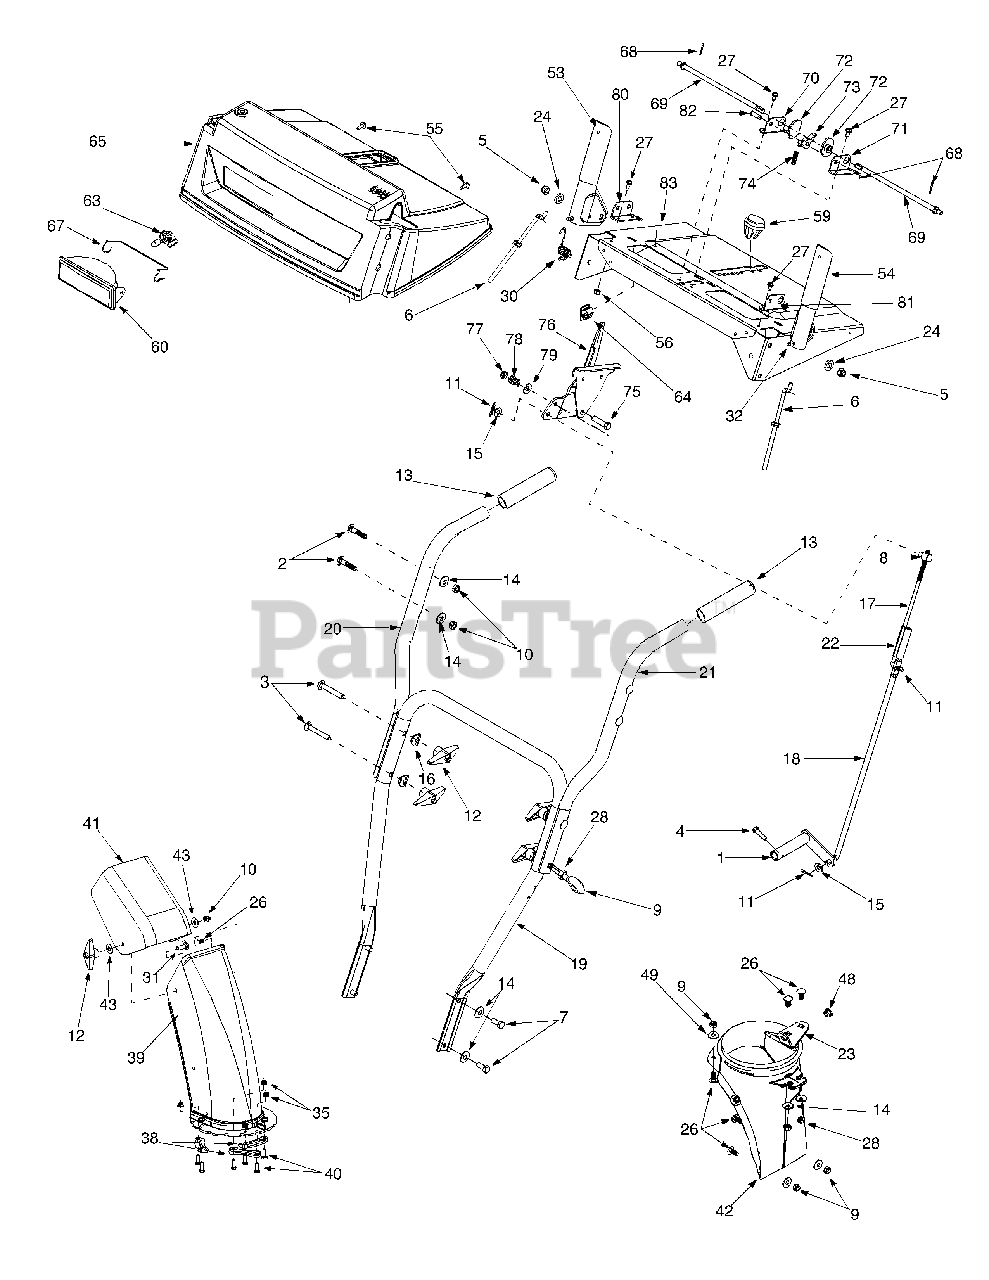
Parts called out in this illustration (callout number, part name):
2	Carriage Bolt 5/16-18 x 1.75"
3	Carriage Bolt 5/16-18 x 2.25"
4	TT Screw 1/4-20 x 1"
5	Hex Lock Nut 5/16-18
6	Z Fitting Cable
7	Hex Screw 5/16-18 x .75"
8	Ferrule
9	Eyebolt
10	Hex Nut 5/16-18
11	Cotter Pin
12	Handle Knob
14	Belleville Washer
15	Flat Washer
16	Saddle Washer
17	Shift Rod: Upper
18	Shift Rod: Lower
24	Washer .72 OD x .135 ID
25	Carriage Bolt: 5/16-18 x 1.5"
26	Carriage Bolt: 5.16-18 x .750"
27	TT Screw: 1/4-20 x 0.5"
28	Hex Nut 5/16-18
30	Torsion Spring
31	Carriage Screws 5/16-18 x 1.0
32	Rubber Bumper
35	Hex Flange Lock Nut
38	Chute Flange Keeper
39	Lower Chute
40	Hex Cap Screw 1/4-20 x .75
41	Upper Chute
43	5/16 Washer
47	Control Cable
48	Plastic Bushing
49	5/16 Washer
53	Handle Assembly RH
54	Handle Assembly LH
55	Special Hex Screw
56	Hex Sems Nut: 1/4-20
57	Hex Nut
59	Shift Knob
60	Lamp Housing
63	Halogen Lamp: 50W, 12V
64	Mounting Clamp
65	Handle Panel
67	Headlight Retainer
68	Cotter Pin: 3/32 x .75
69	Cam Rod
72	Cam Handle Lock
73	Handle Lock Pawl
74	Compression Spring: .36 x 1.0
75	Hex Cap Screw: 3/8-24 x 1.5
78	Comp. Spring: .39 x .6 x .88
79	Bell Washer
82	Clevis Pin
